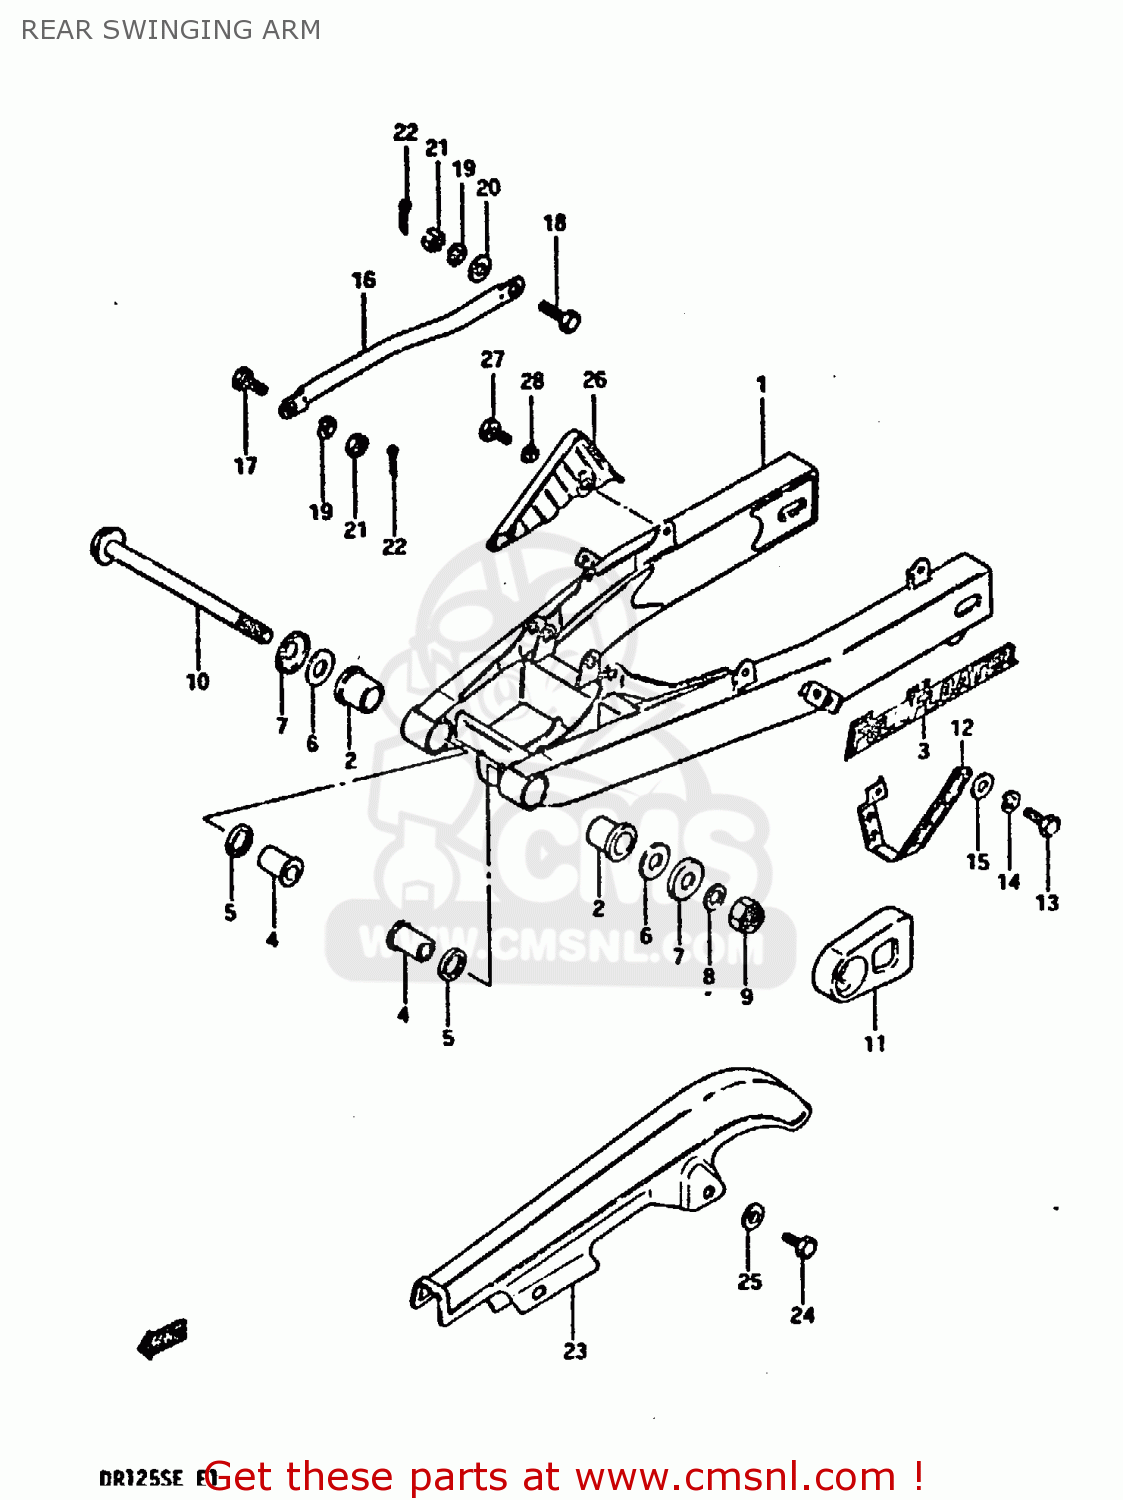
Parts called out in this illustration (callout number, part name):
1	SWING ARM ASSEMBLY,REAR
2	BUSHING,REAR SWING ARM PIVOT
3	EMBLEM,SWING ARM
4	SPACER,RR SWGARM PIVOT
5	SEAL,OIL(20X27X5)
6	WASHER
7	CVR,RR SWGARM DUST SEAL(OD:40)
8	WASHER
9	NUT 14MM
10	SHAFT,REAR SWING ARM
11	BUFFER,CHAIN TOUCH DEFENSE
12	GUIDE,CHAIN
13	BOLT 8X12
14	LOCK WASHER
15	WASHER
16	TORQUE LINK,REAR
17	BOLT(8X22)
18	BOLT(8X26.5)
19	LOCK WASHER
20	WASHER
21	NUT
22	PIN 20X20
23	CASE,CHAIN
24	BOLT 6X8
25	WASHER
26	GUARD,PILLION FOOT
27	BOLT 6X8
28	WASHER
